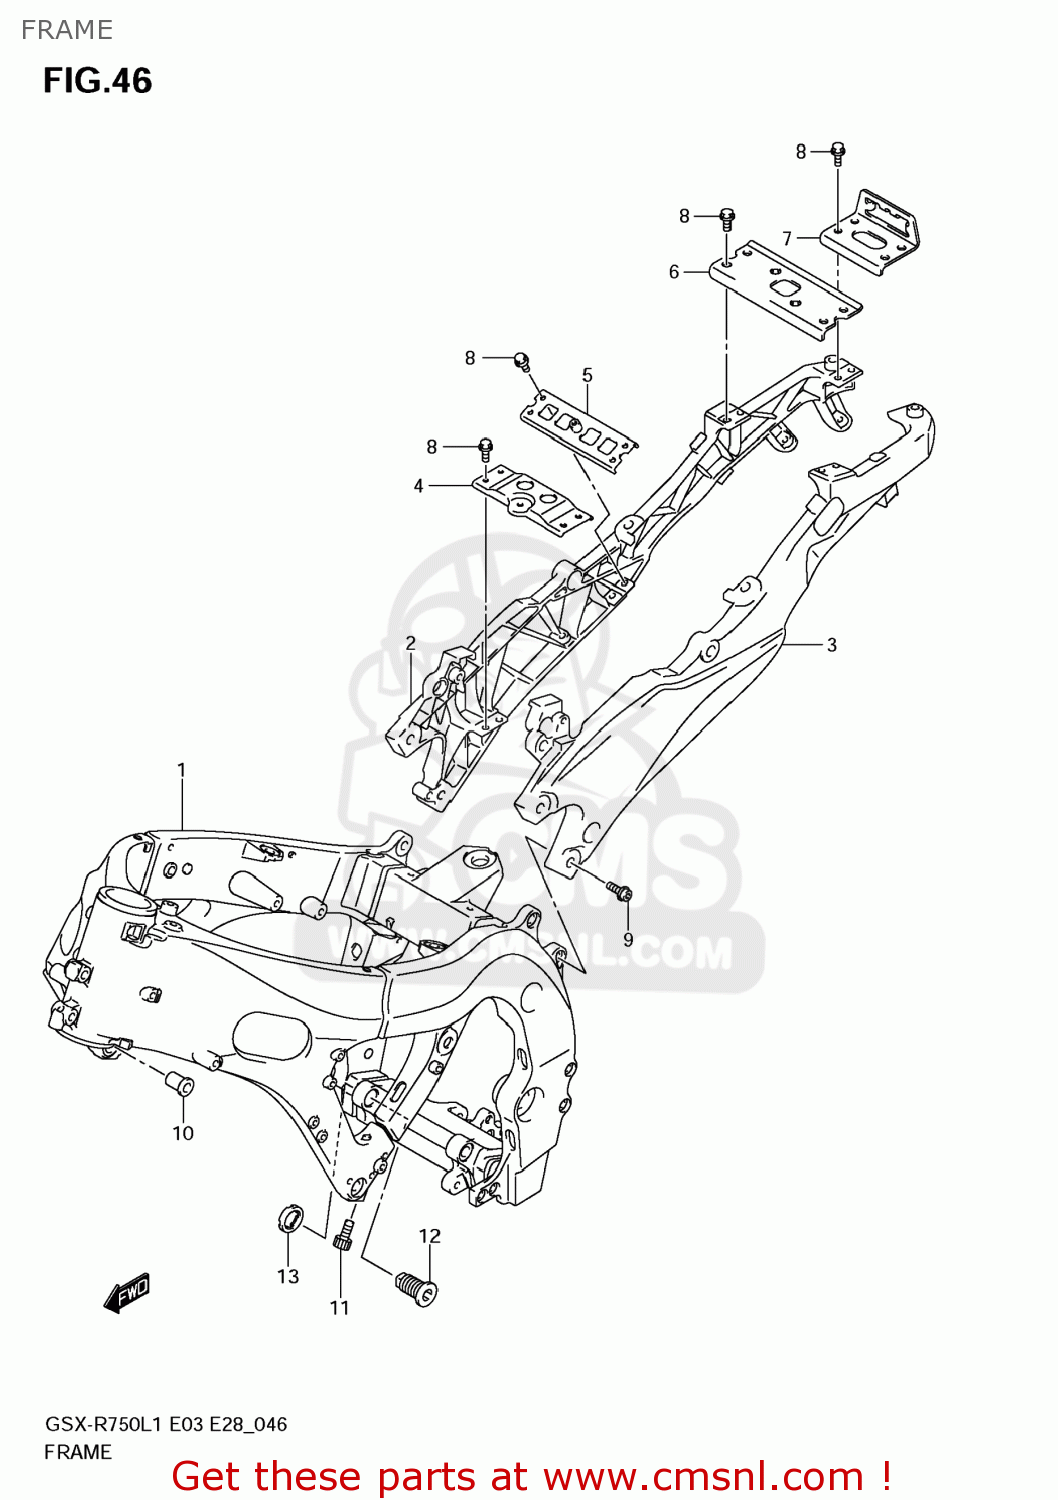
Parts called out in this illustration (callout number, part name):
1	FRAME(BLUE)
2	RAIL,SEAT,R(BLACK)
3	RAIL,SEAT,L(BLACK)
4	BRIDGE,SEAT RAIL FR
5	BRIDGE,SEAT RAIL LWR
6	BRIDGE,SEAT RAIL UPR
7	BRIDGE,SEAT RAIL RR
8	BOLT(6X12)
9	BOLT,SEAT RAIL
10	SPACER,ENGINE MOUNTING
11	BOLT(8X32)
12	BOLT,CRANK CASE ADJUST
13	NUT,ADJUST BOLT
